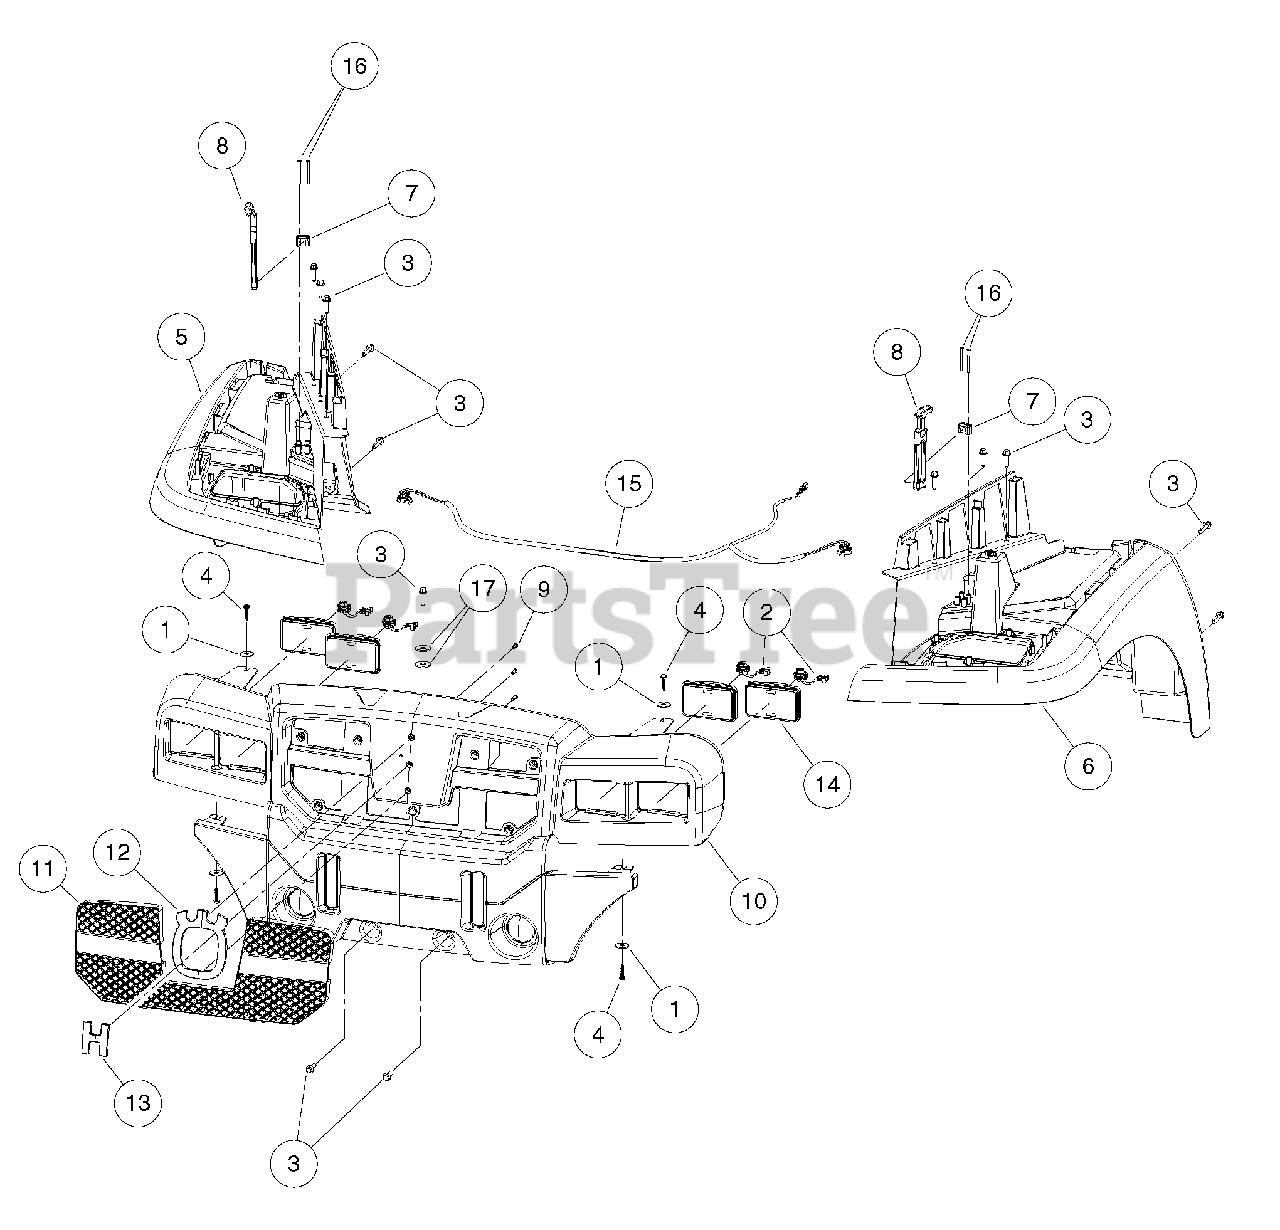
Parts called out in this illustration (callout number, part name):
1	Washer, 5/16 Type B Flat
2	Connector Harness Assembly, Headlight
3	Screw, M8X1.25X30, Hex
4	Screw,m6,torx,interlock,thread
5	Fender, Front, Pass, AWD
6	Fender, Front, Drv, AWD
7	Bracket, Latch, Draw
8	Latch, Draw, Hood
9	Screw, D50x16, Torx PN Hd PT
10	Fascia, Husqvarna
11	Grill, Husqvarna
12	Emblem, Husqvarna, Outer
13	Emblem, Husqvarna, Inner
14	Headlamp, 3x5 Rectangular
15	Harness, Bct/huv Restyle Headlight
16	Screw, #8x2.00 AB Thd, Hex Hd
17	Washer, 3/8 Type B Flat
